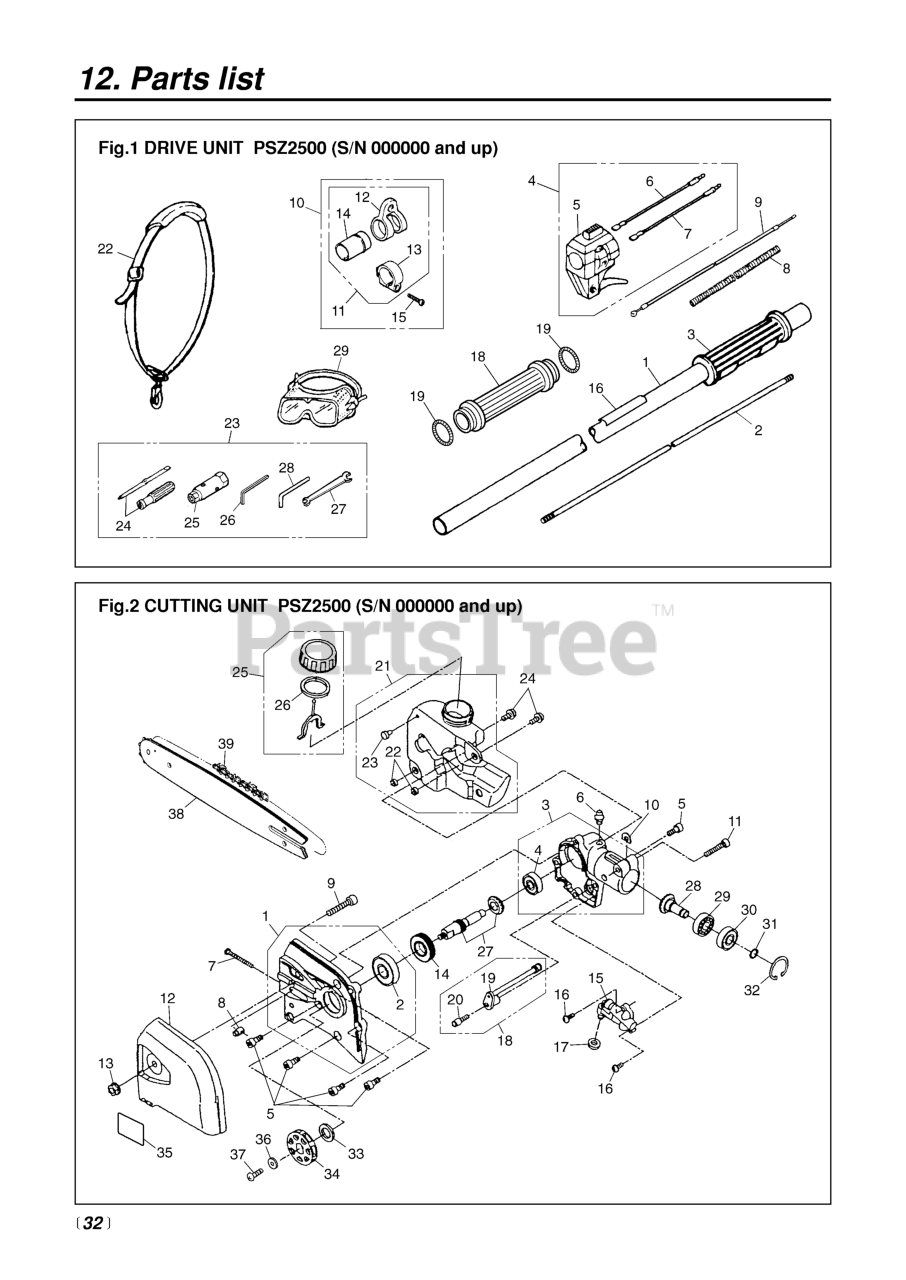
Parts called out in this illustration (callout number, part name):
1-1	PIPE COMP (REPLACES -12100)
1-2	SHAFT (RPLS -12212)
1-3	GRIP
1-5	LEVER (USE 848-8R2-0313)
1-6	CORD (A), BLACK
1-7	CORD (B), RED
1-8	TUBE (RPLS 4900-72141)
1-9	CABLE (RPLS 5580-83100)
1-10	HANGER ASSEMBLY
1-11	HANGER COMPLETE
1-12	HANGER
1-13	CLAMP
1-14	SLEEVE
1-15	SCREW, M5 x 25
1-16	PLATE, NAME
1-18	GRIP
1-19	SPRING
1-22	STRAP ASSY.
1-24	SCREWDRIVER
1-25	SOCKET
1-26	WRENCH (TOOL)
1-27	SPANNER, 8 X 10 (RPLS 2540- )
1-28	BAR
1-29	GOGGLE
2-2	BEARING
2-3	GEARCASE COMP (RIGHT)
2-5	BOLT, M5 x 12
2-6	FITTING, GREASE
2-7	SCREW
2-8	NUT
2-9	BOLT, M6 x 30
2-10	SHIM
2-12	COVER, CHAIN
2-13	NUT
2-14	GEAR, WORM
2-15	PUMP ASSY, OIL
2-16	SCREW, M4 x 10
2-17	GASKET
2-18	PIPE ASSY, OIL
2-19	PIPE, OIL
2-20	FILTER
2-21	TANK ASSY, OIL
2-22	COLLAR
2-23	VALVE
2-24	SCREW, M5 X 12
2-25	CAP ASSY, OIL
2-26	GASKET, OIL CAP
2-27	SHAFT, GEAR
2-28	GEAR, BEVEL
2-29	BEARING (RPLS T3403-13530)
2-31	RING, SNAP (RPLS T3300-13330)
2-32	RING, SNAP, M24 x 1.2
2-33	COLLAR
2-34	SPROCKET
2-35	LABEL (PSZ2500)
2-36	WASHER
2-37	SCREW
2-39	12
